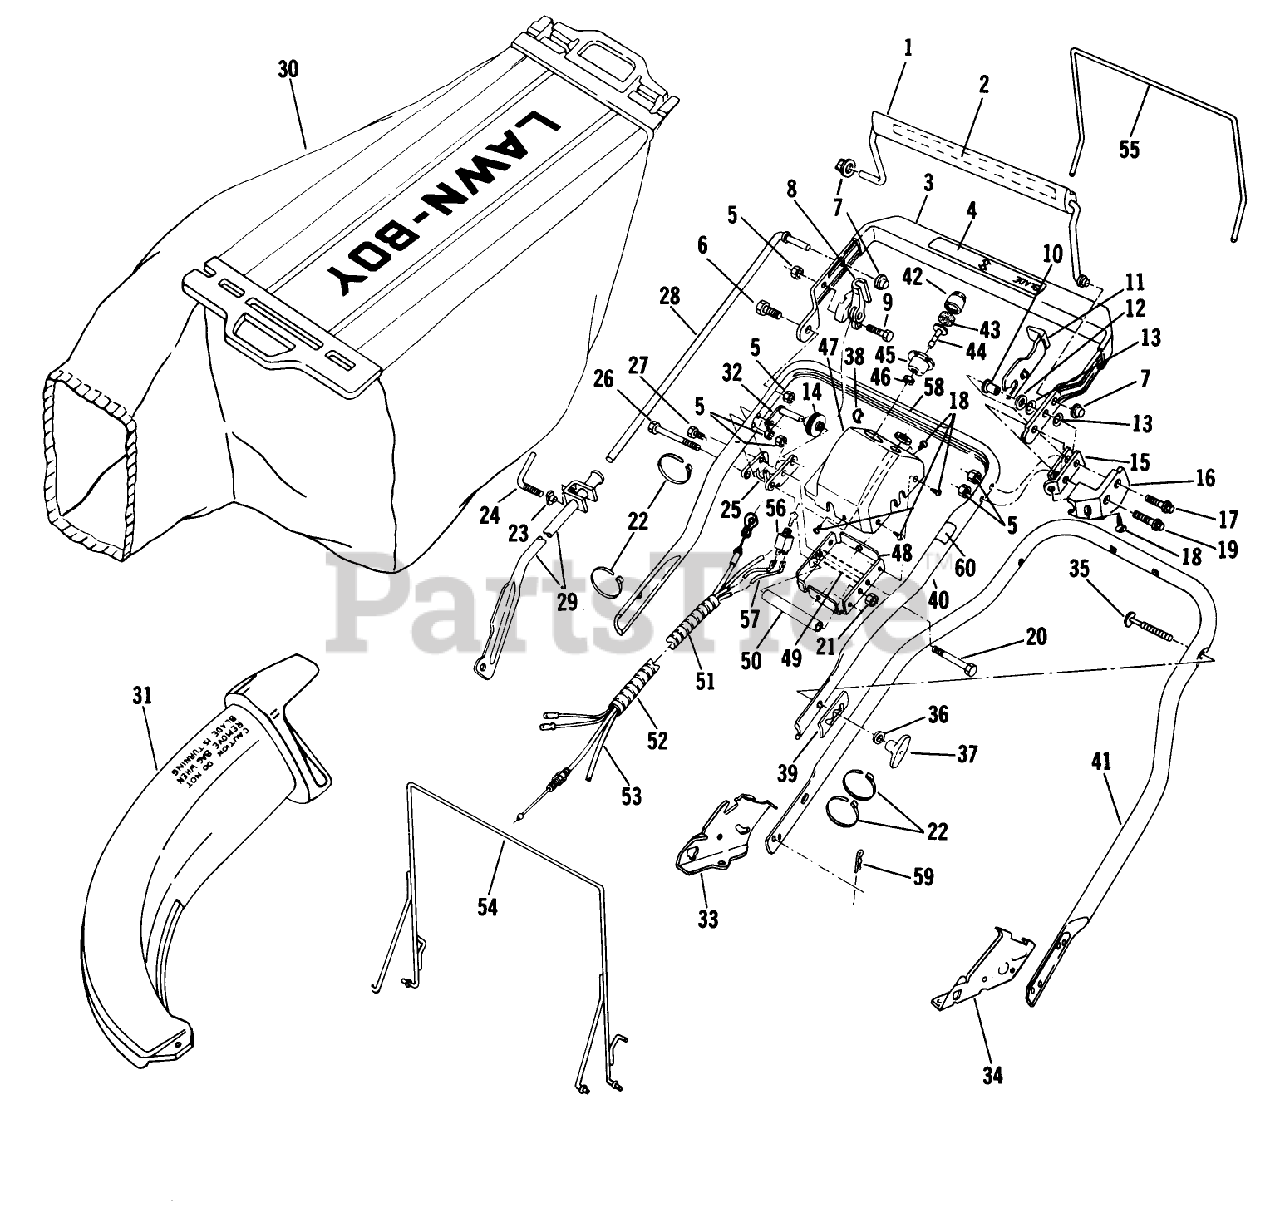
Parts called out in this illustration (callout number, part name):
5	LOCKNUT E
6	BOLT
10	SPACER
12	WASHER M
15	DOWN STOP
16	LOCKOUT GUARD
17	BOLT SHOU
18	Screw-"Taptite"
19	SCREW
26	BOLT-CONSOLE
35	BOLT QUALITY
36	WASHER-CURVED
37	NUT-WING
39	BRACKET R/B 613462
43	FILTER S
46	LOCKNUT S
49	SPACER
54	HANGER AY
55	HANGER
59	HAIR PIN
